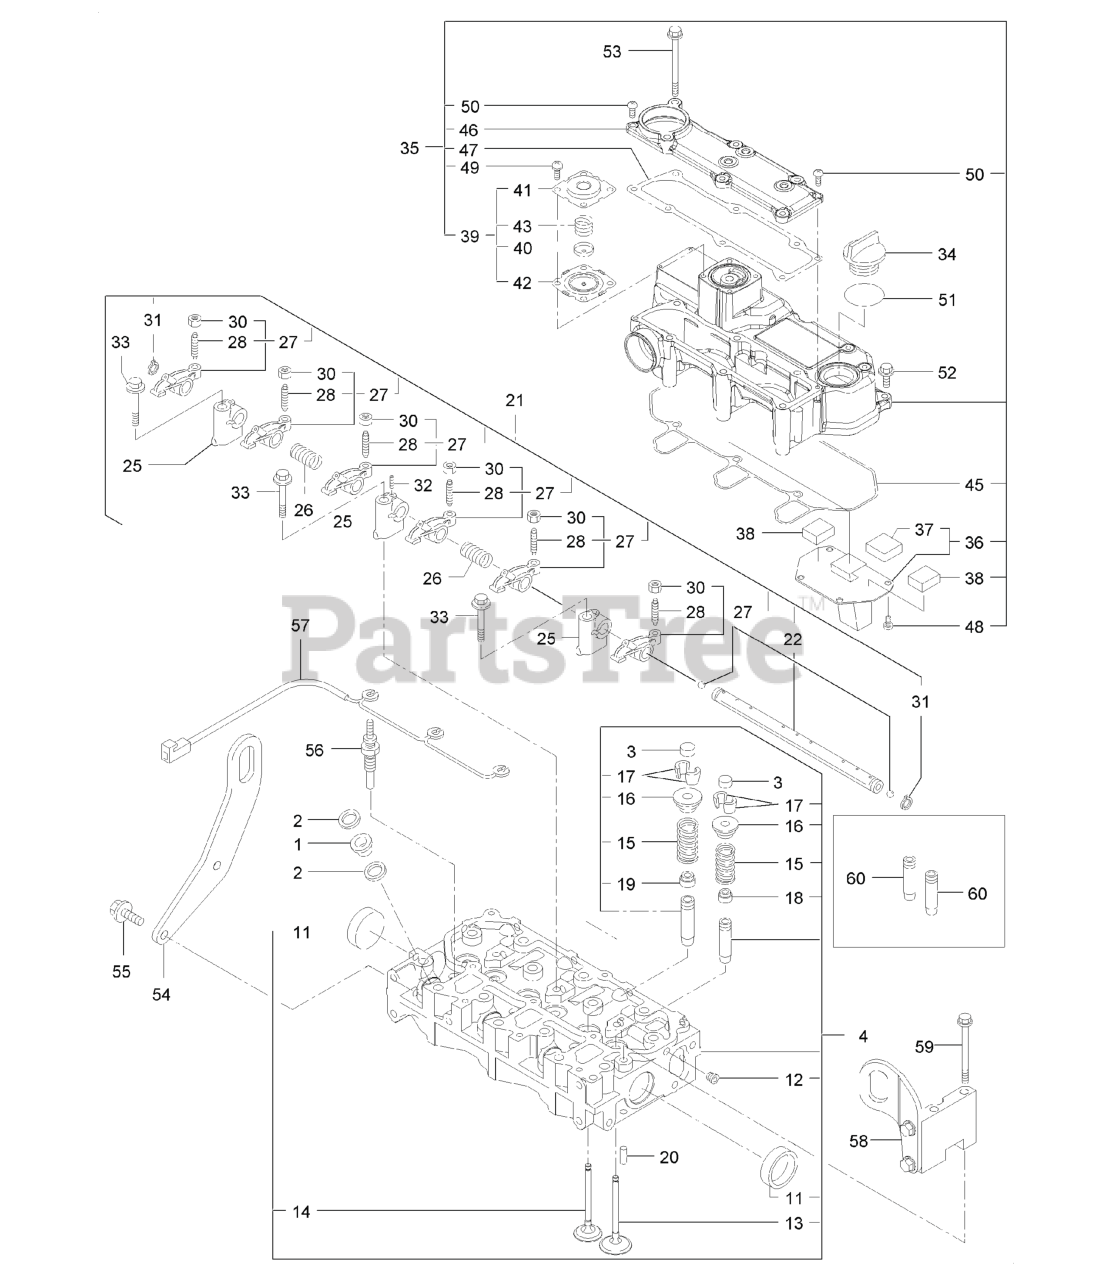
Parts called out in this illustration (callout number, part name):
1	PROTECTOR-NOZZLE
2	GASKET-NOZZLE
3	CAP-VALVE
4	Head ASM-Cylinder
11	PLUG-CUP
13	VALVE-SUCTION
14	VALVE, EXHAUST 3
15	SPRING-VALVE
16	RETAINER
18	SEAL-STEM, VALVE
19	SEAL-STEM, VALVE
20	PIN-SPRING
21	SUPPORT ASM-ROCKER
22	SHAFT ASM-ROCKER
25	SUPPORT-ROCKER ARM
26	SPRING-ROCKER
27	ARM ASM-ROCKER
28	SCREW-ADJUST, VALVE
34	COVER-FILLER
35	BONNET ASM
36	PLATE-BAFFLE
37	BAFFLE-BREATHER
38	BAFFLE-BREATHER
39	DIAPHRAGM ASM
40	PLATE-DIAPHRAGM
41	COVER-DIAPHRAGM
42	DIAPHRAGM
43	SPRING-DIAPHRAGM
45	GASKET-BONNET
46	COVER ASM-BONNET
54	LIFTER-ENGINE
56	PLUG-GLOW
57	CONNECTOR-GLOW PLUG
58	LIFTER ASM
